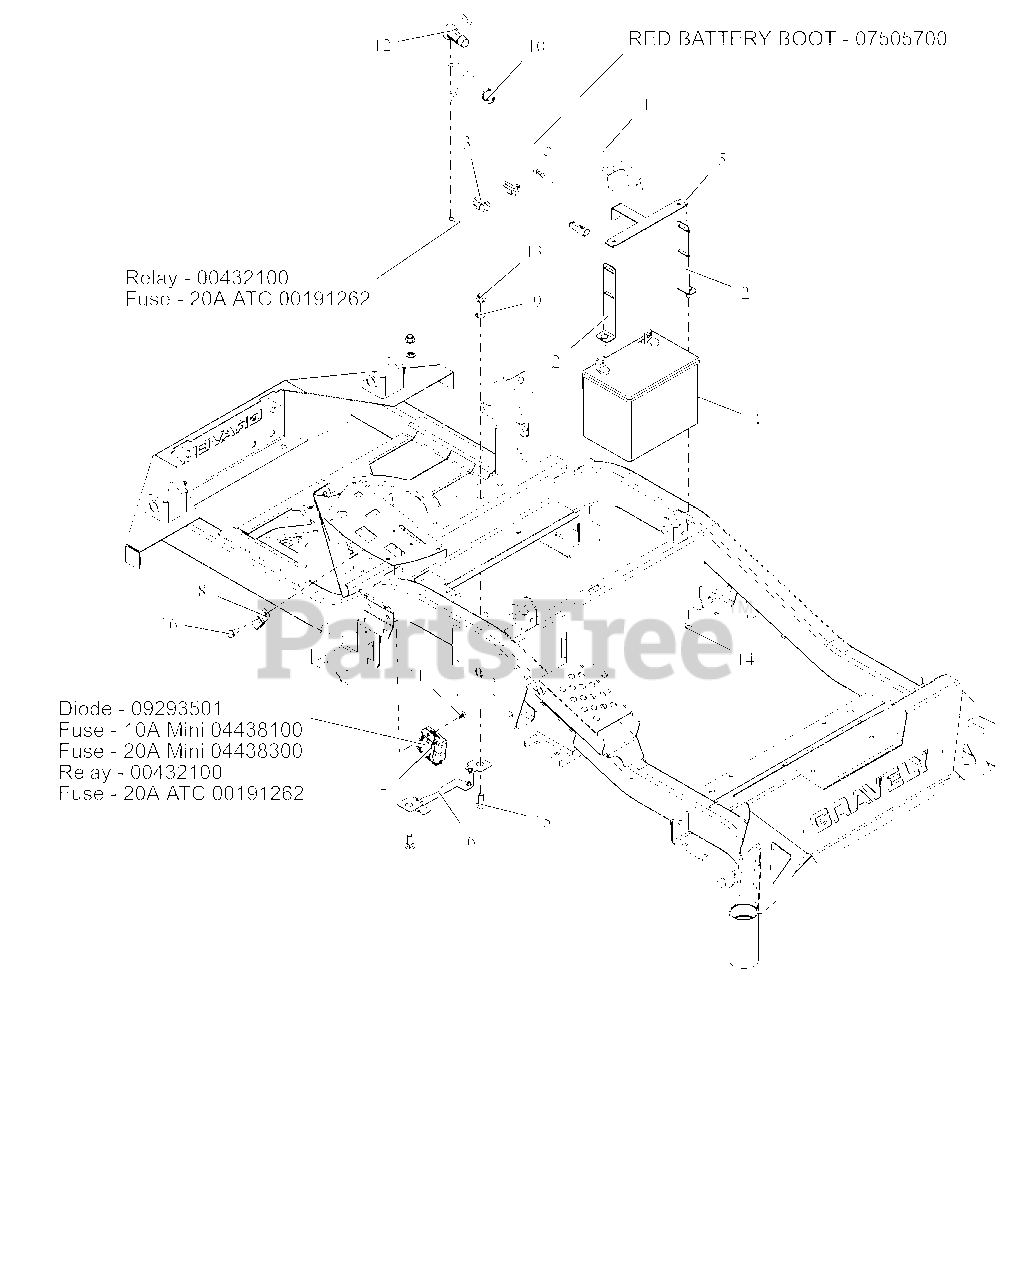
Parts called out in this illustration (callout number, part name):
1	HARNESS, BATTERY HD
1	INSULATOR
2	WMT,BATTERY MOUNT HOLD DOWN
3	HARNESS, STARTER ADAPTER
3	RELAY,SEALED W/DIODE
3	FUSE, 20 AMP BLADE S/O
4	BATTERY, 300 CCA 10U1L
5	BRKT, BATTERY TIE DOWN
6	GUARD, ELECTRICAL HARNESS
7	HARNESS, WIRE
7	DIODE, CONNECTOR SHELL
7	FUSE,10 AMP MINI-ATC
7	FUSE,20 AMP MINI ATC
7	RELAY,SEALED W/DIODE
7	FUSE, 20 AMP BLADE S/O
9	NUT-PUSH .38 DIA. PAL ZINC
10	CABLE TIE W/ TREE (.25 HOLE)
11	RIVET, .25 NYLON PANEL
12	BOOT, .65ID POS
13	NUT,NYL-FLG .38-16 GF ZCC
14	NUT-LK-TOP-FLG .250-20 GF ZCC
15	BLT, RHSN .38-16X1.00 G5 ZCC
16	SCR,TAP .312-18X.75 HWH TR ZCC
